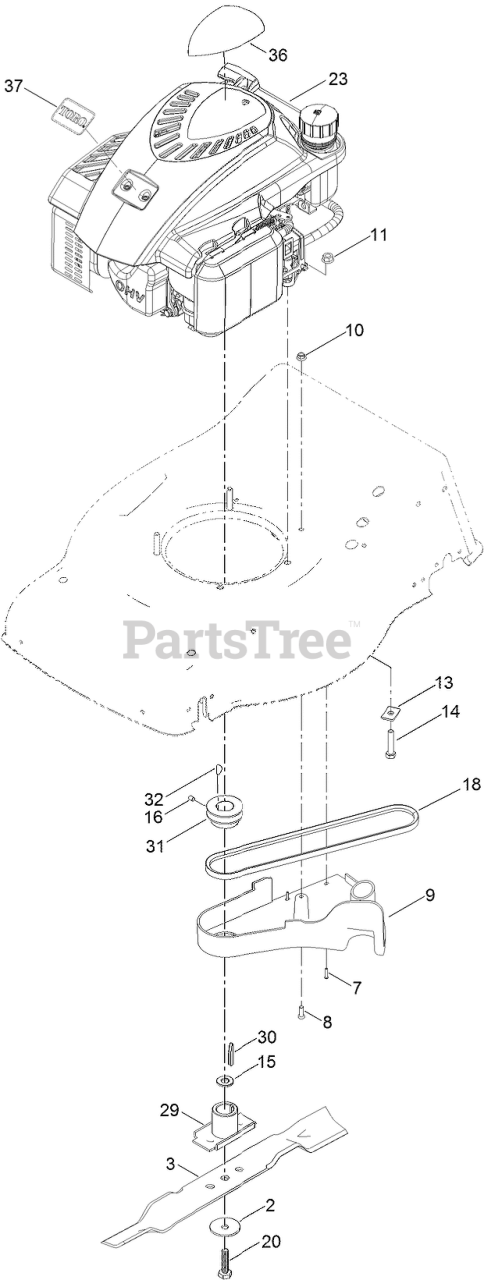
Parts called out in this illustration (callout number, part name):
2	WASHER-DISHED
3	BLADE-MULCH
7	SCREW-SELF DRIVING
8	SCREW-TOOTH
9	COVER-PULLEY, BELT
10	NUT-LOCK, FLANGE
11	NUT-LOCK, FLANGE
13	WASHER-SQUARE
14	BOLT-BLADE
15	SHEATH-BLADE
16	SCREW-GRUB
18	BELT-TRIANGLE
20	BOLT-BLADE
23	ENGINE-1P65FC
29	SUPPORT-BLADE
30	KEY-FLAT
31	PULLEY-DRIVE
32	KEY-WOODRUFF
36	DECAL-SHROUD
37	LOGO -TORO ( 3-IN-1 MODELS)
